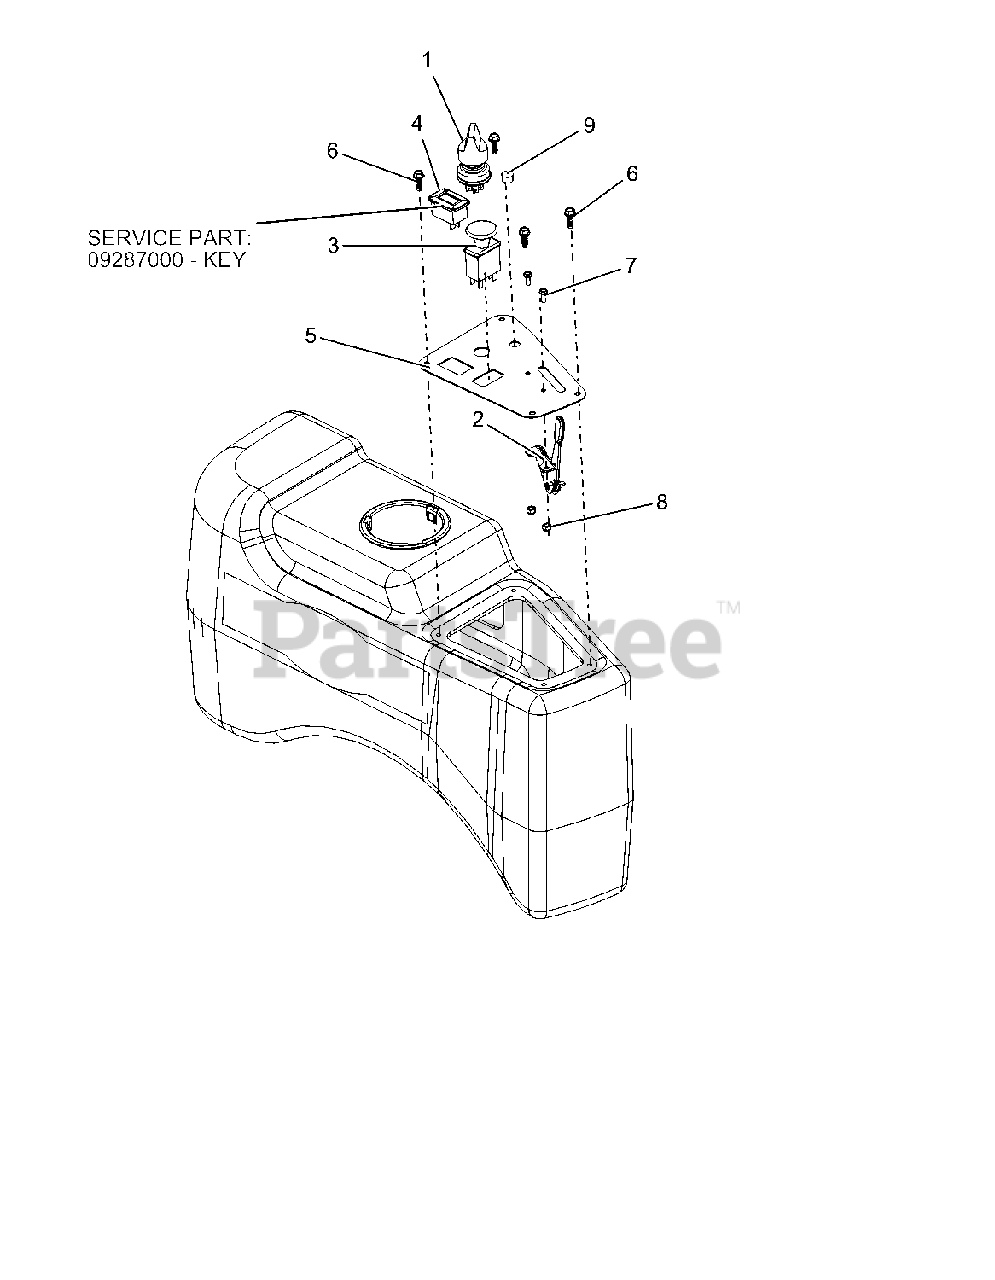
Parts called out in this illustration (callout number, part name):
1	SWITCH, IGNITION
2	CABLE, CONTROL
3	SWITCH, CLUTCH
4	KEY
4	METER, HOUR W/MAINTENANCE
5	PANEL, CONTROL
6	SCR-PLASTITE .25-10X.75 YWZC
7	@SCR-MCH 10-24X.50 HWH YWZC
8	NUT-LK-NYL #10-24 YWZC
9	PLUG, HOLE .50 DIA
